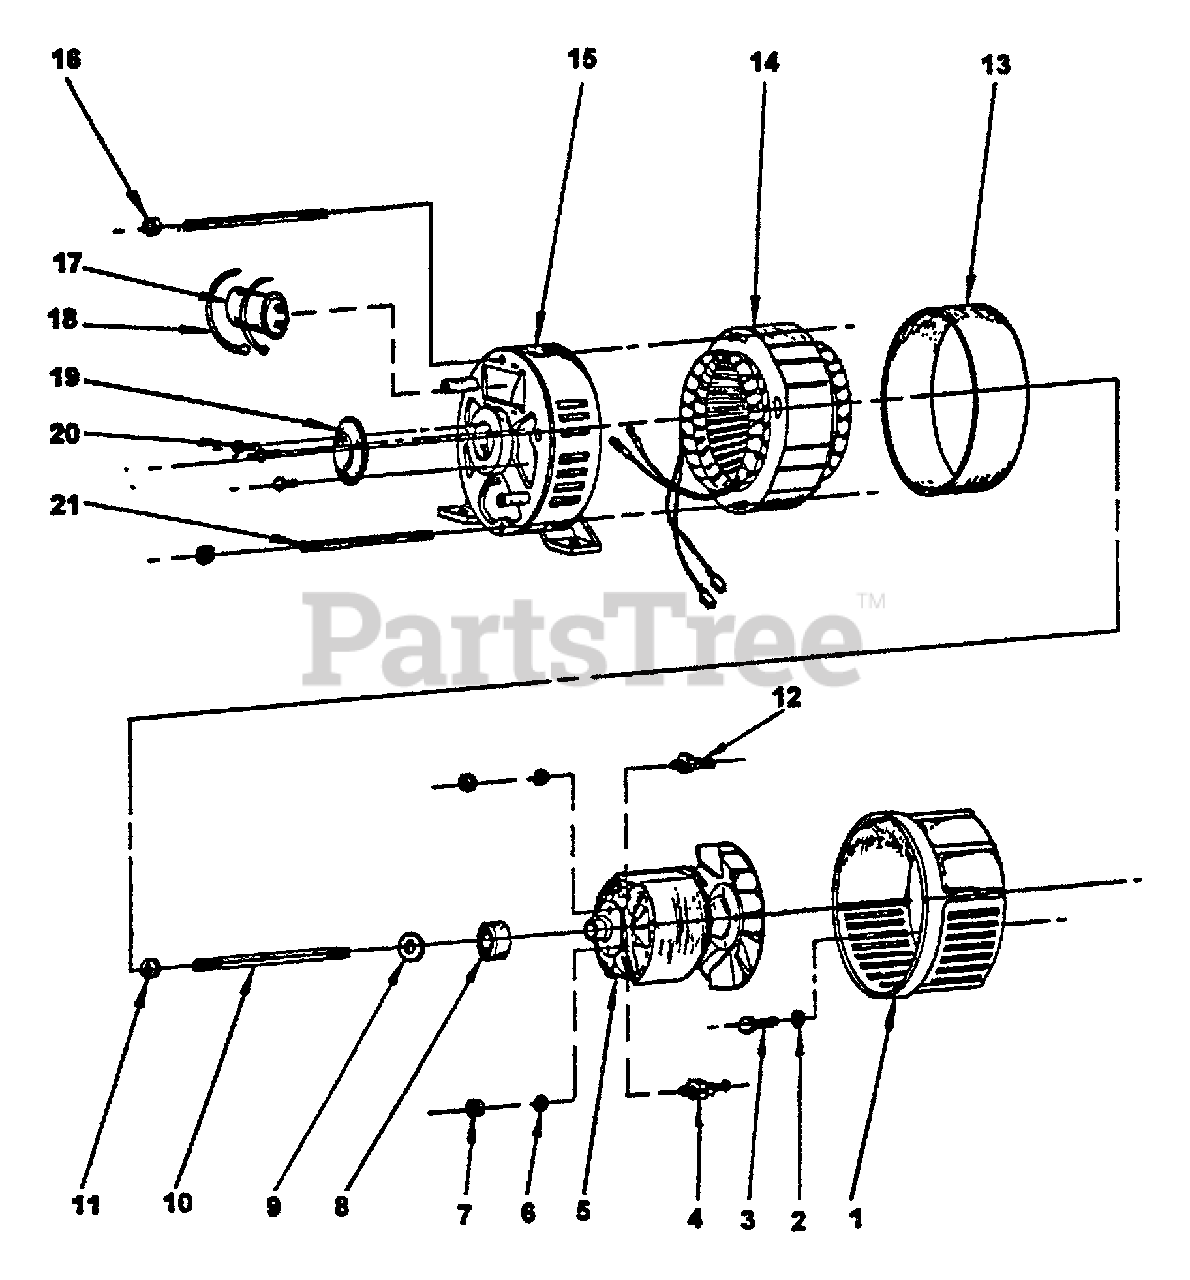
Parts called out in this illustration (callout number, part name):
1	DRIVE END ADAPTER CASTING
2	LOCKWASHER - 5/16"
3	SCREW - 5/16-24 X 1"
4	DIODE
5	ROTOR ASSY
6	LOCKWASHER, DIODE
7	NUT, DIODE
8	BEARING
9	LOCKWASHER - 5/16"
10	ROTOR THRU BOLT
11	NUT - 5/16-24 -- KEPS
12	DIODE
13	BAND, COVER
14	STATOR ASSY
15	CASTING, BEARING
16	NUT - 1/4-20 -- KEPS
17	CAPACITOR - 50UF 370V
18	TIE, CABLE
19	COVER, BEARING
20	SCREW - 10-24 X 1/2"
21	BOLT, STATOR
